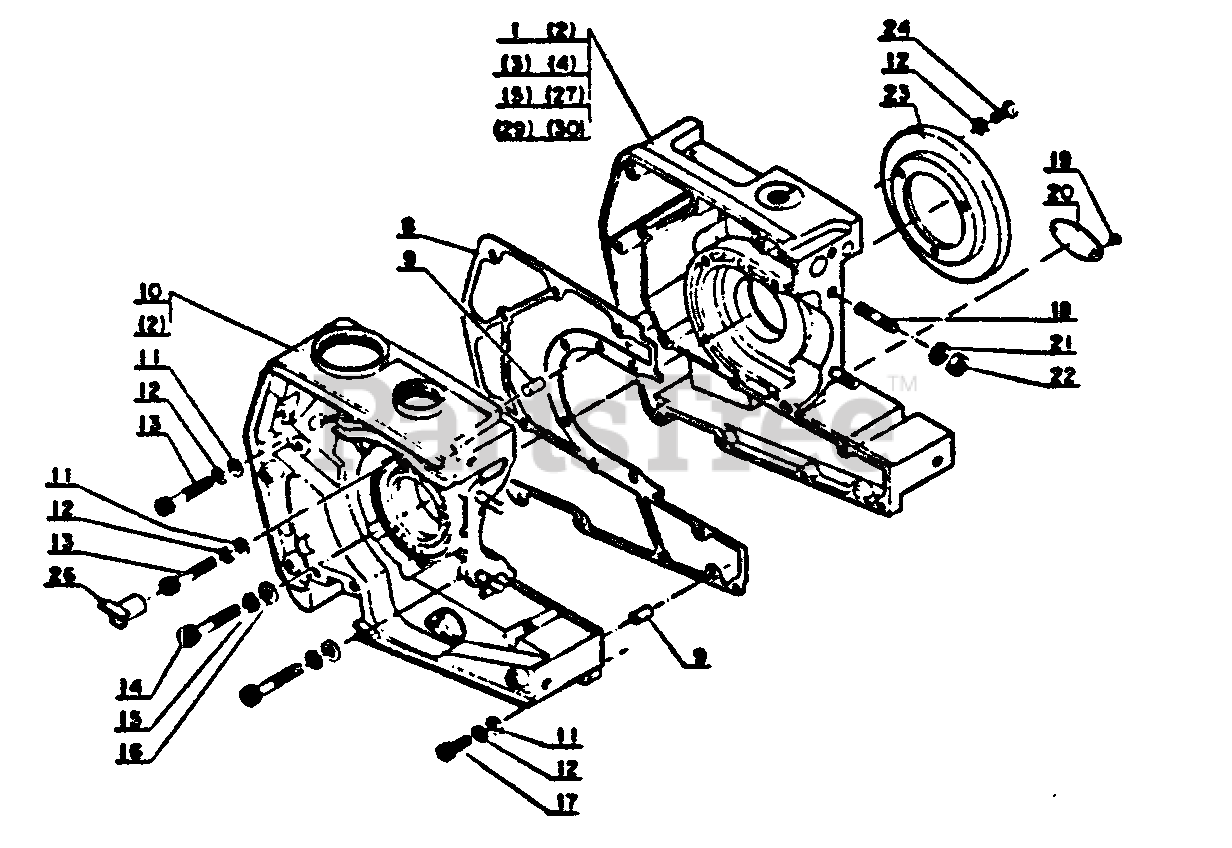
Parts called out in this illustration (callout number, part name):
1	CRANKCASE KIT
8	GASKET, CRANKCASE
9	PIN, LOCATING 5×10
10	CRANKCASE KIT
11	WASHER 4 MM
12	WASHER, SPRING 4 MM
13	BOLT - 4×33
14	BOLT - 5×30
15	WASHER, SPRING 5
16	WASHER
17	BOLT - 4×20
18	STUD
19	RIVET
20	MODEL PLATE
21	WASHER, FLAT 5.5×10×0.8
22	NUT M5
23	SEAL, DUST
24	SCREW 4×10
26	CLIP, CORD
